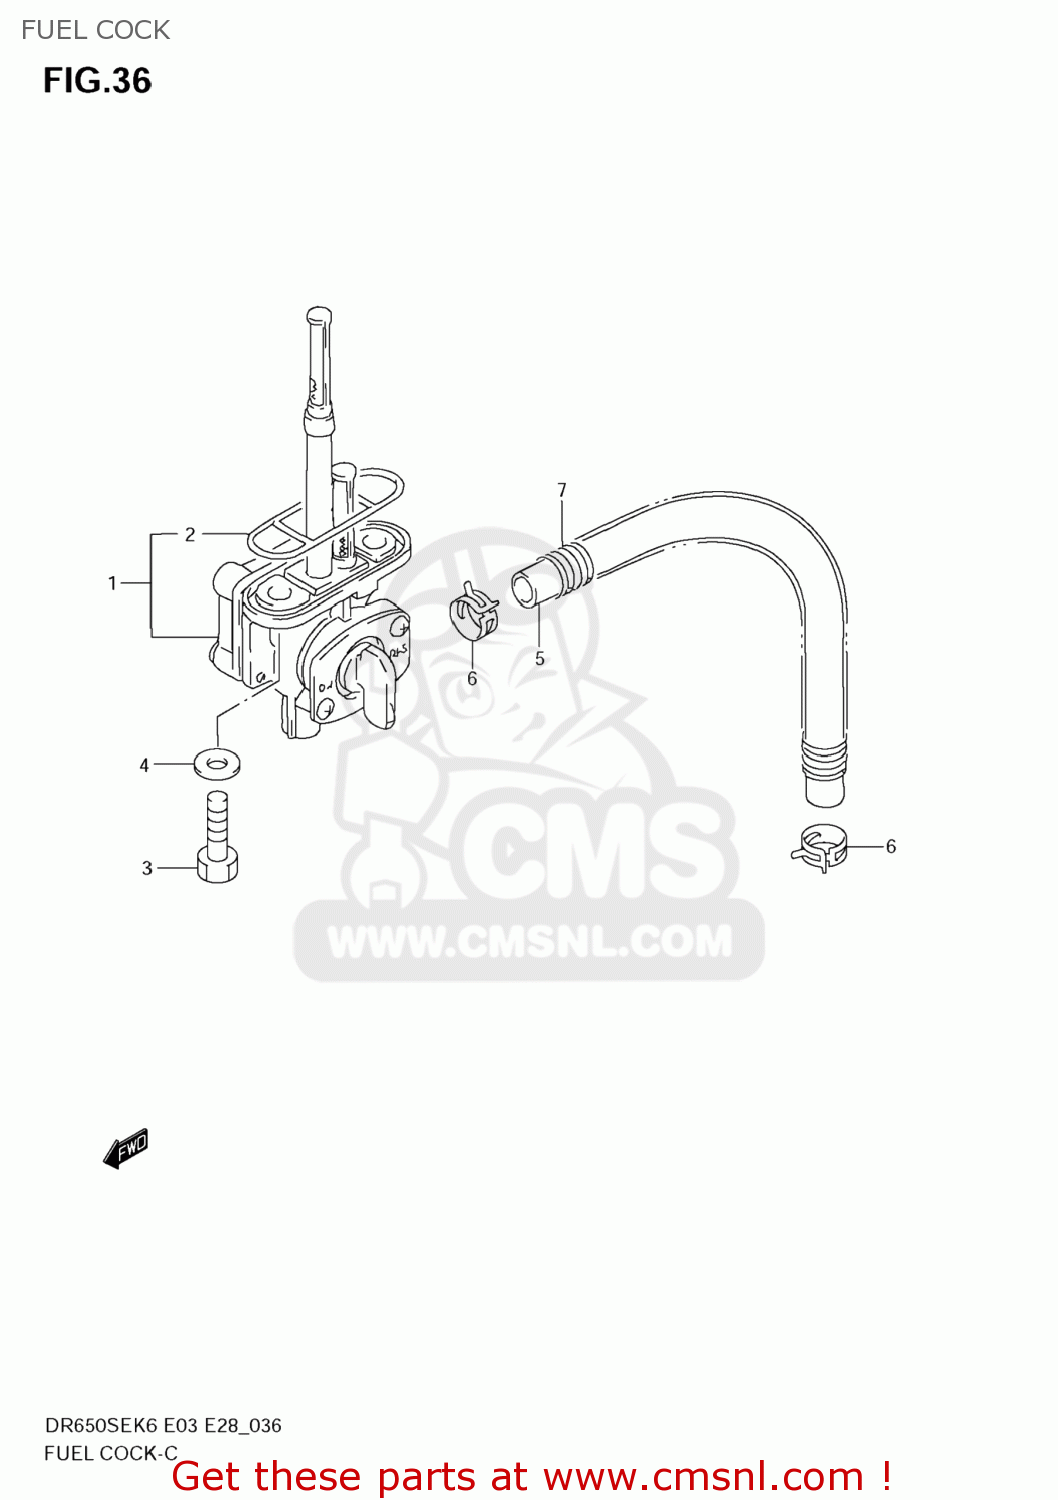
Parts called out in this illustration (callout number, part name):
1	COCK ASSY,FUEL
2	GASKET,JOINT (NAS)
3	BOLT(6X20)
4	GASKET(6.4X11.5X0.8) (NAS)
5	HOSE,FUEL
6	CLIP
7	SPRING
